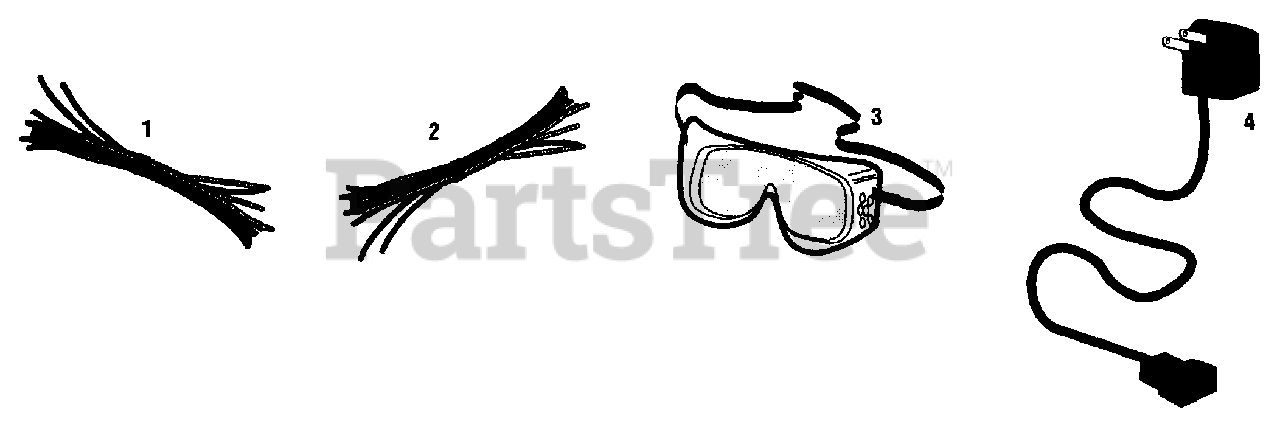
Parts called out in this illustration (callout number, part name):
1	Trimmer String Kit, .155"
2	Trimmer String Kit, .130"
3	Safety Goggles
4	Battery Charger
